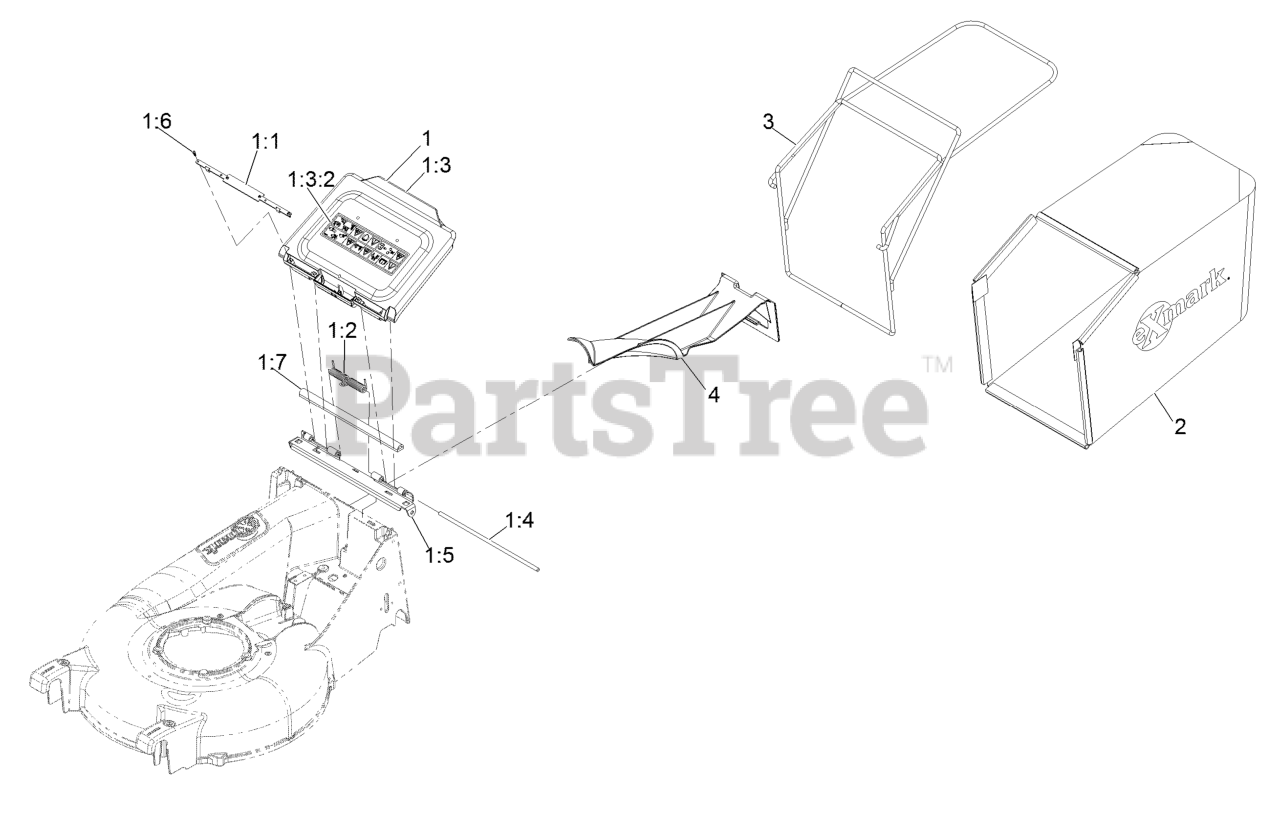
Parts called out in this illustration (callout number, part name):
1	Door ASM
1:1	Plate, Door Cover
1:2	Spring-Plastic Door
1:3	ASM-Door & Decal
1:3:2	Decal-Warning
1:4	Pin-Door Pivot
1:5	Bracket-Door Pivot
1:6	Scr,TAP,6-19X7/16,Phph,Stl, Rohs
1:7	Seal-Epdm Foam Bulb
2	Bag-21 Grass
3	Wld-Bag Frame
4	Plug,Mulch
